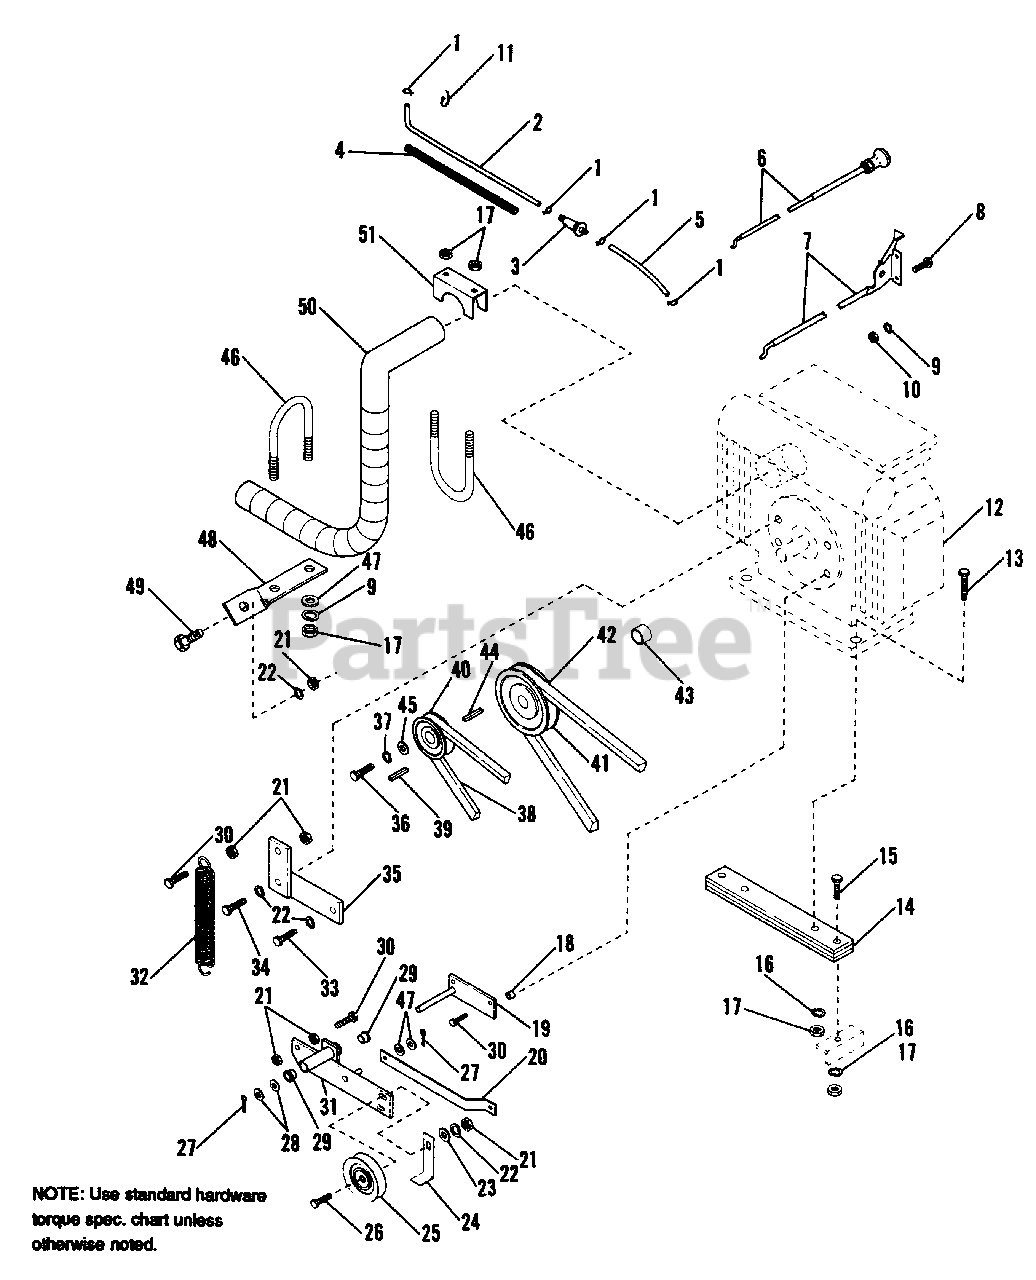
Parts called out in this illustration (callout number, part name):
1	CLAMP, Hose
2	HOSE, Fuel, 12" (Cut to length)
3	FILTER, Fuel
4	TUBING, Flexible
5	HOSE, Fuel, 5"
6	CHOKE CABLE
7	THROTTLE CABLE
8	SCREW, Pan Head Phillips, #10-24 x 1
9	LOCKWASHER, Spring #10
10	NUT, Hex #10-24
13	CAPSCREW, Hex 5/16-18 x 1-3/4
14	BAR ASSY., Spacer
15	CAPSCREW, Hex 5/16-18 x 1-1/2
16	LOCKWASHER, Spring 5/16
17	NUT, Hex 5/16-18
19	IDLER PIVOT ASSY.
20	LINK, Clutch
21	NUT, Hex 3/8-16
22	LOCKWASHER, Spring 3/8
23	WASHER, Plain
24	RETAINER, Belt
25	V-PULLEY, Idler, PTO
26	CAPSCREW, Hex 3/8-16 x 1-1/2
28	WASHER, Plain
29	BEARING, Flanged
30	CAPSCREW, Hex 3/8-16 x 1-3/4
31	IDLER ARM ASSY.
33	CAPSCREW, Hex 3/8-16 x 1
34	CAPSCREW, Hex 3/8-16 x 1-1/4
35	SPRING ANCHOR ASSY.
36	CAPSCREW, Hex 7/16-20 x 1-1/4
37	LOCKWASHER, Spring 7/16
38	V-BELT, Traction
39	KEY, Parallel
40	V-PULLEY, Traction
41	V-PULLEY, PTO
42	V-BELT, PTO
43	SPACER, Engine
44	KEY, Square
45	WASHER, Plain
47	WASHER, Plain
48	BRACKET, Muffler
49	CAPSCREW, Hex 3/8-16 x 3/4
50	ELBOW ASSY., Muffler
51	CLAMP ASSY., Exhaust
